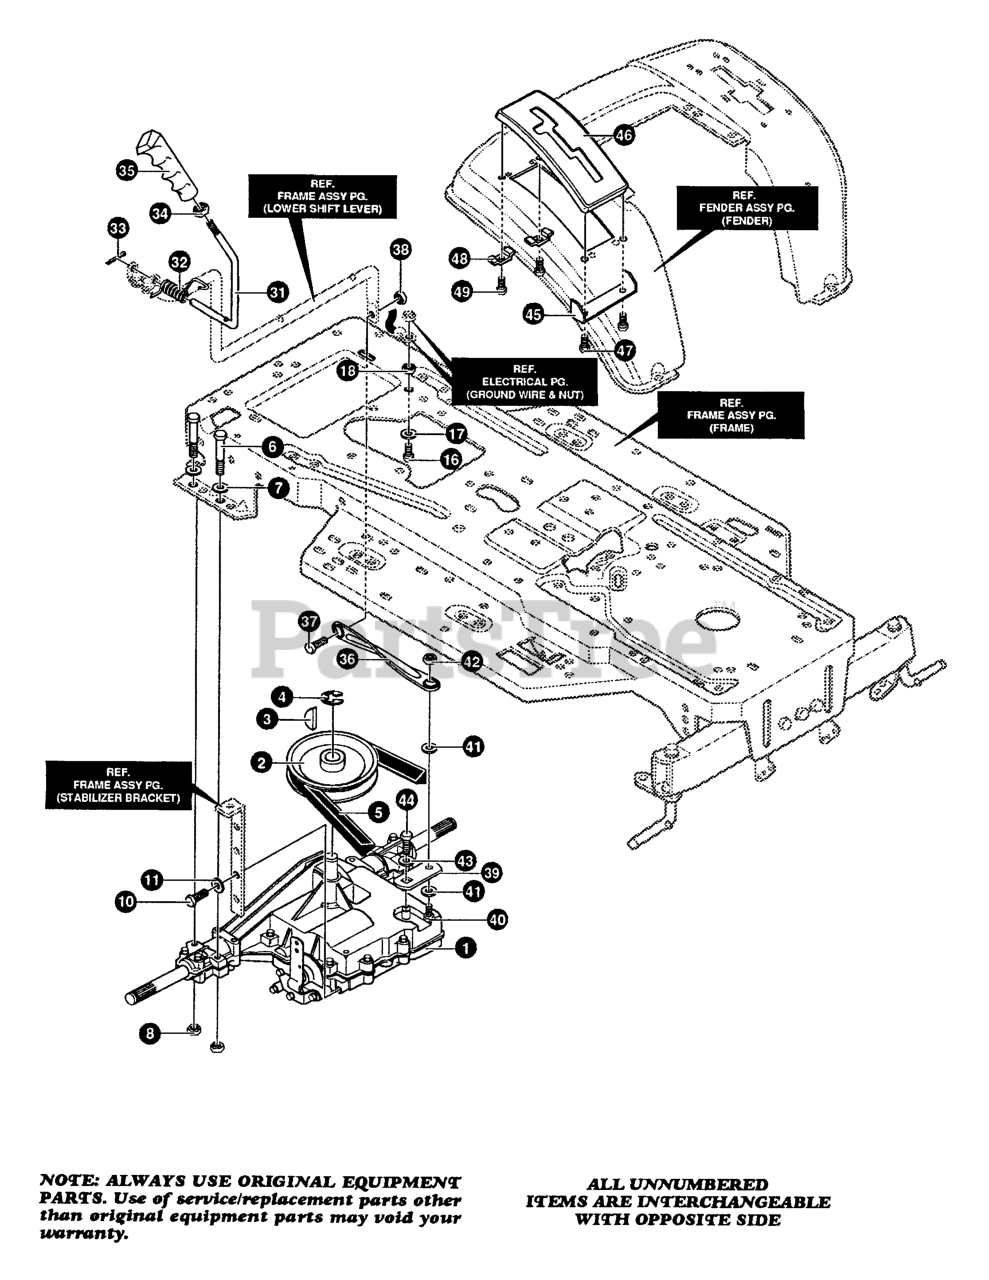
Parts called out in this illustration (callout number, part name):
1	TRANSAXLE, 4WS **
2	PULLEY, 6.6
3	KEY, HI-PRO 606
4	RING, RETEX
5	BELT, V 4L 87.25
6	SCREW, 5/16-18 x 2.50
7	WASHER, FLAT .344 x .69 x .065
8	NUT, 5/16-18
10	SCREW, 5/16-18 x 0.75
11	WASHER, .328 x .60 x .09
16	SCREW, 5/16-18 x 0.75
17	WASHER, .320 x .61 x .03
18	NUT, 5/16-18
31	LEVER, SHIFT UPPER
32	SPRING, TORSION
33	PIN, COTTER
34	NUT, 1/2-13
35	HANDLE 1/2-13
36	LINK, TIE ROD SHIFT
37	SCREW, 3/8-16 x 1.25
38	NUT, 3/8-16
39	BRACKET, SHIFT
40	SCREW, 3/8-16 x 1.25
41	WASHER, FLAT .406 x .81 x .065
42	NUT, 3/8-16
43	WASHER, .750 x .250
44	SCREW, 1/4-28 x .75
45	BRACKET COVER
46	COVER PLASTIC
47	SCREW, 1/4-15 x .44/.53
48	CLAMP, SPRING
49	SCREW, 1/4-15 x .44/.53
